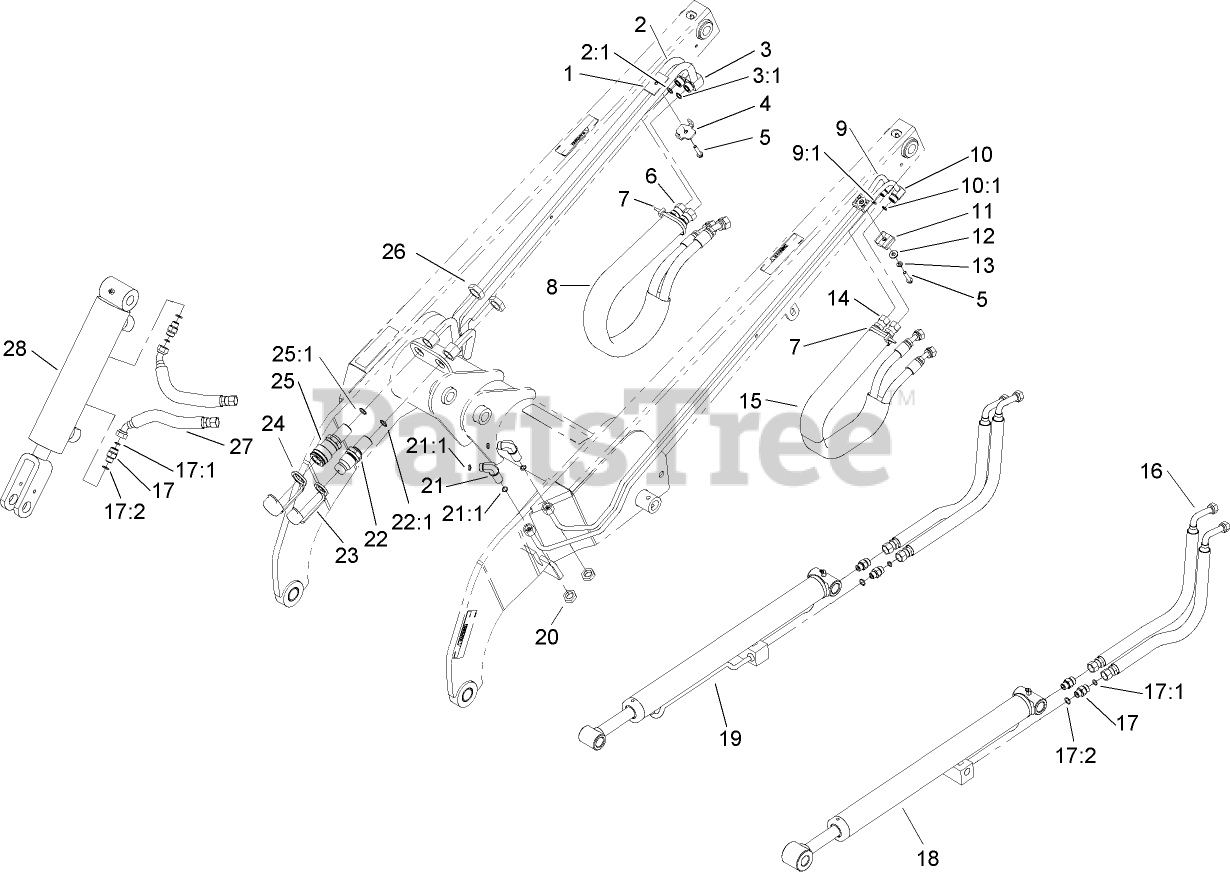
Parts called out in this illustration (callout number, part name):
1	SPACER-HARDLINE
2	HYD TUBE ASM
2:1	O-RING
3	HYD TUBE ASM
3:1	O-RING
4	PLATE-CLAMP, TUBE
5	SCREW-HWH
6	HOSE-HYD
7	TIE-CABLE
8	SLEEVE-PROTECTIVE
9	HYD TUBE ASM
9:1	O-RING
10	HYD TUBE ASM
10:1	O-RING
11	CLAMP-TUBE
12	WASHER-FLAT
13	WASHER-LOCK
14	HOSE-HYD
15	SLEEVE-PROTECTIVE
16	HOSE-HYD
17	FITTING-STRAIGHT
17:1	O-RING
17:2	O-RING
18	LH LIFT CYLINDER ASM
19	RH LIFT CYLINDER ASM
20	NUT-LOCK
21	UNION-BULKHEAD
21:1	O-RING
22	BULKHEAD NIPPLE ASM
22:1	O-RING
23	CAP-DUST, NIPPLE
24	CAP-DUST, COUPLER
25	BULKHEAD COUPLER ASM
25:1	O-RING
26	NUT-LOCK, BULKHEAD
27	HOSE-HYD
28	TILT CYLINDER ASM
